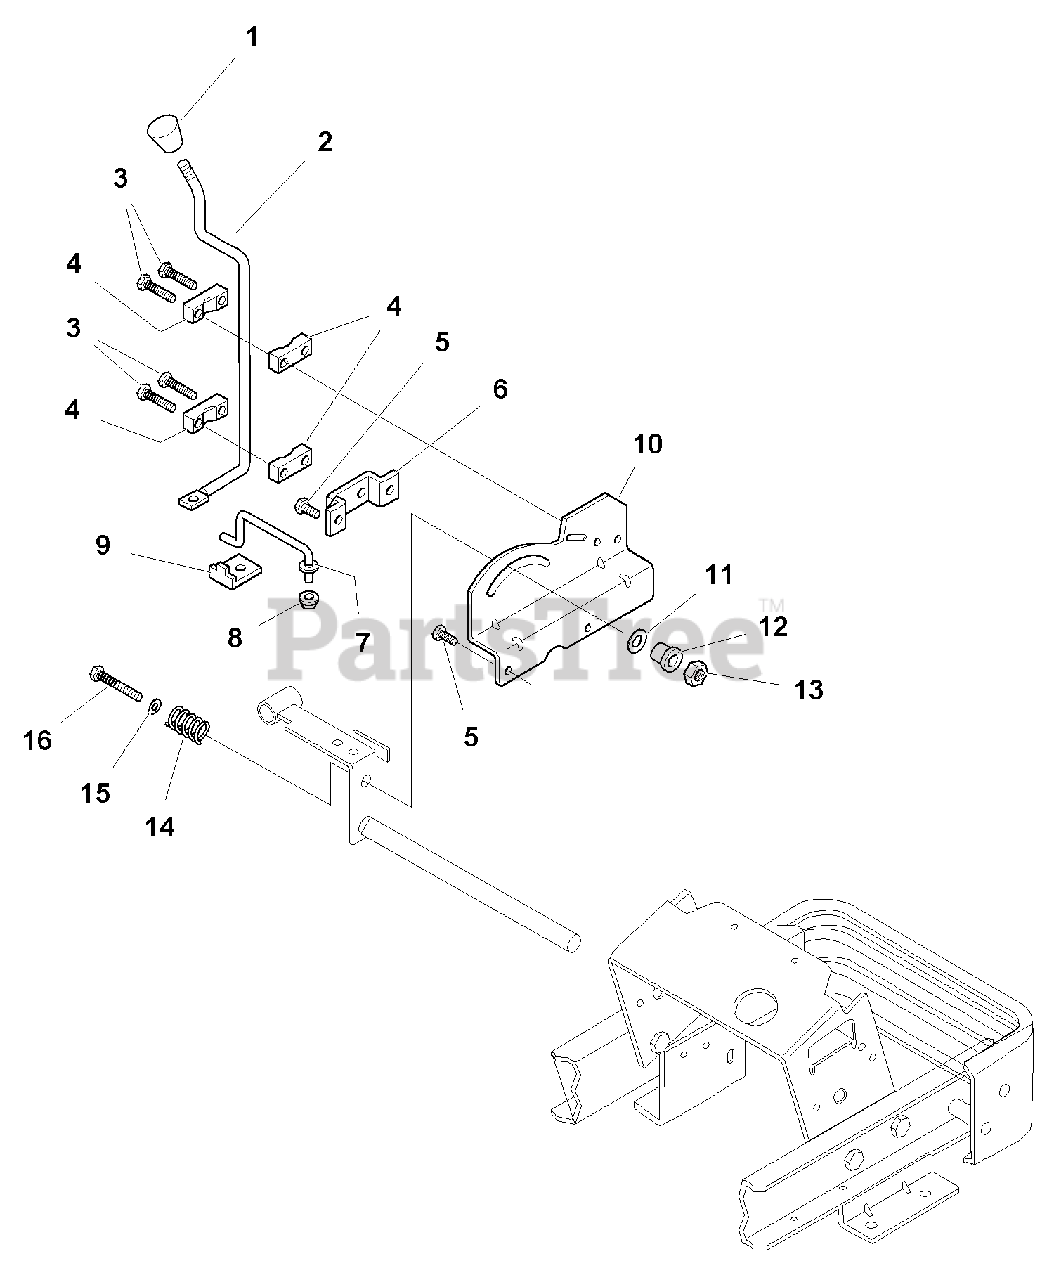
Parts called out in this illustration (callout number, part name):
2	ROD, Two Speed
3	CAPSCREW, Taptite, 5/16-18 x 1-1/2
4	BEARING HALF, Nylon
5	CAPSCREW, Taptite, 5/16-18 x 3/4
6	BRACKET, Two Speed
7	ROD, Two Speed, Lower
8	PUSH NUT
9	QUADRANT, Two Speed
10	BRACKET, Slotted (Cruise & Two Speed)
11	WASHER, 1/2 x 1-1/4
13	NUT, Hex, Nylon, 5/16-18
14	SPRING, Compression
15	WASHER, 5/16
16	CAPSCREW, Hex Head, 5/16-18 x 2-1/2
